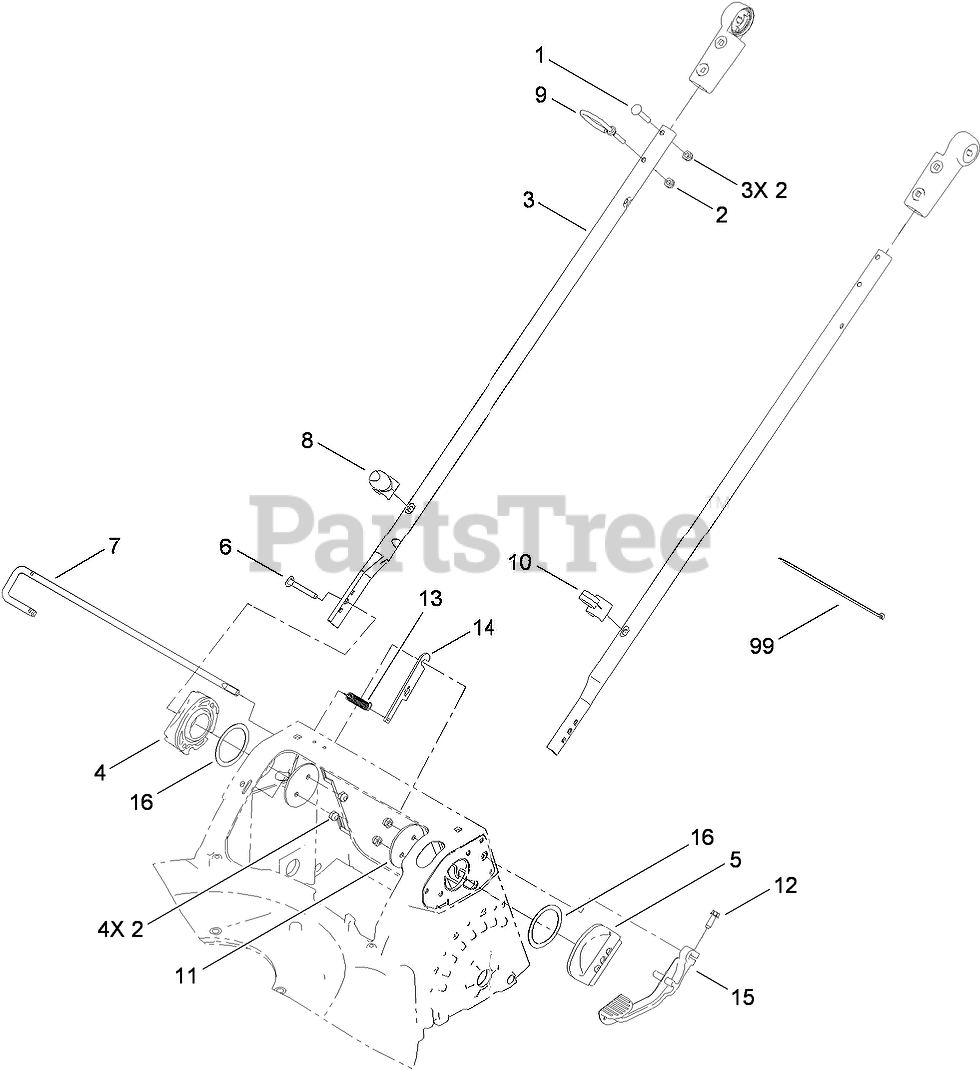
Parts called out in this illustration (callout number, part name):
1	SCREW-CARR
2	NUT-LOCK, NI
3	TUBE-LOWER
4	MOUNT-HANDLE, RH
5	MOUNT-HANDLE, LH
6	SCREW
7	ROD-RELEASE, HANDLE
8	GUIDE-ROPE, LOWER
9	GUIDE-ROPE, UPPER
10	Guide-Cable
12	SCREW-HWHTF
13	SPRING-EXTENSION
14	PLATE-ROD, RELEASE
15	LEVER-RELEASE
16	WASHER-NYLON
99	TIE-CABLE
